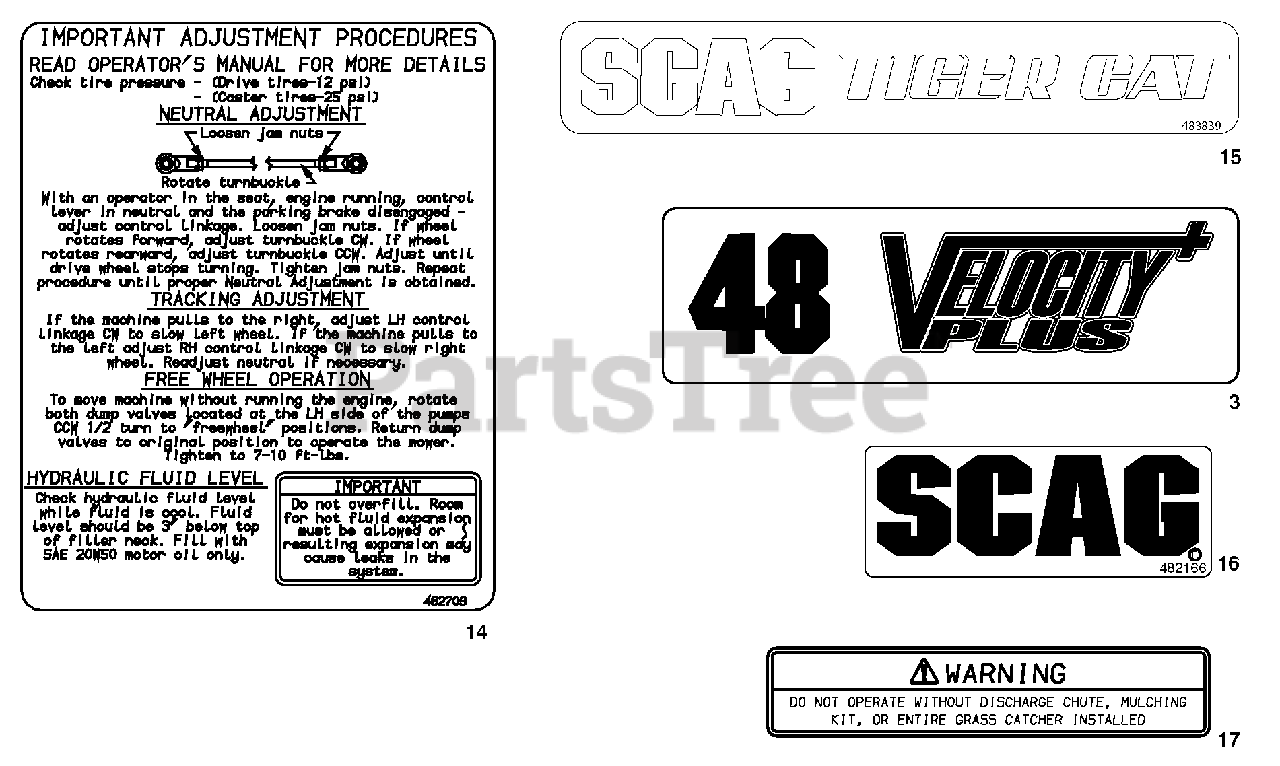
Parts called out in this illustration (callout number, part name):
3	Decal, 48V
3	Decal, 52V
3	Decal, 61V
14	Decal, Seat Support
15	Decal, Rear Bumper
15	Decal, Scag Tiger Cat EFI
16	Decal, Front Footplate
17	Decal, Discharge Chute
